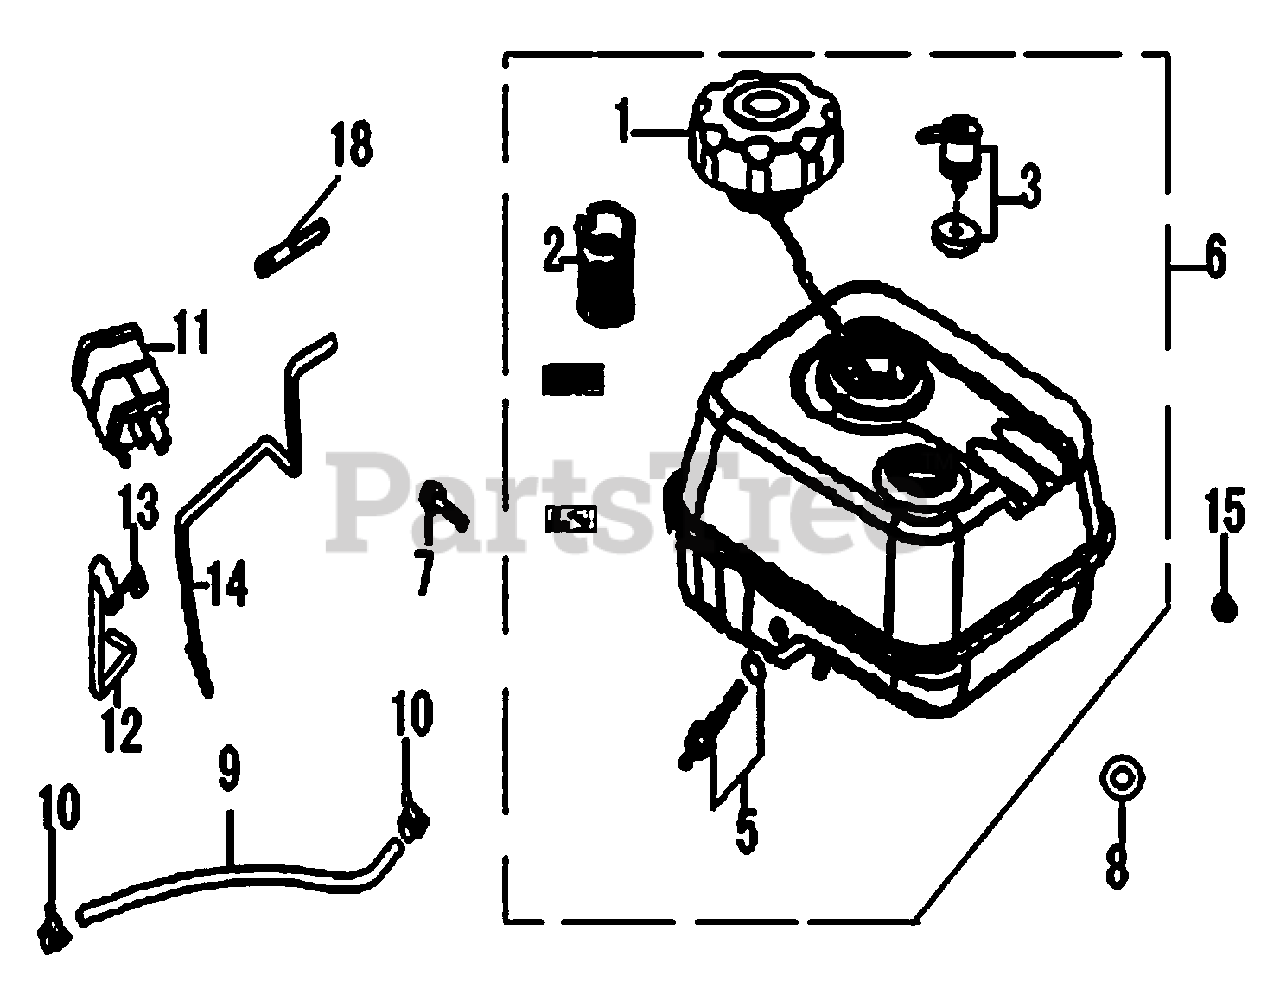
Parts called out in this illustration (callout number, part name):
1	CAP, FUEL FILLER
2	FILTER,FUEL
3	GAS VALVE, FUEL TANK
5	JOINT ASSY., FUEL TANK
6	TANK ASSY, COMP., FUEL
7	BOLT,FLANGE, 6X25
8	WASHER, RUBBER
9	HOSE, FUEL (TUBE)
10	CLAMP/COLLAR
11	CARBON CANISTER ASSY
12	HOSE, FORMED
14	HOSE, FORMED
15	NUT, FLANGE, 6MM
18	CABLE CLEAT
